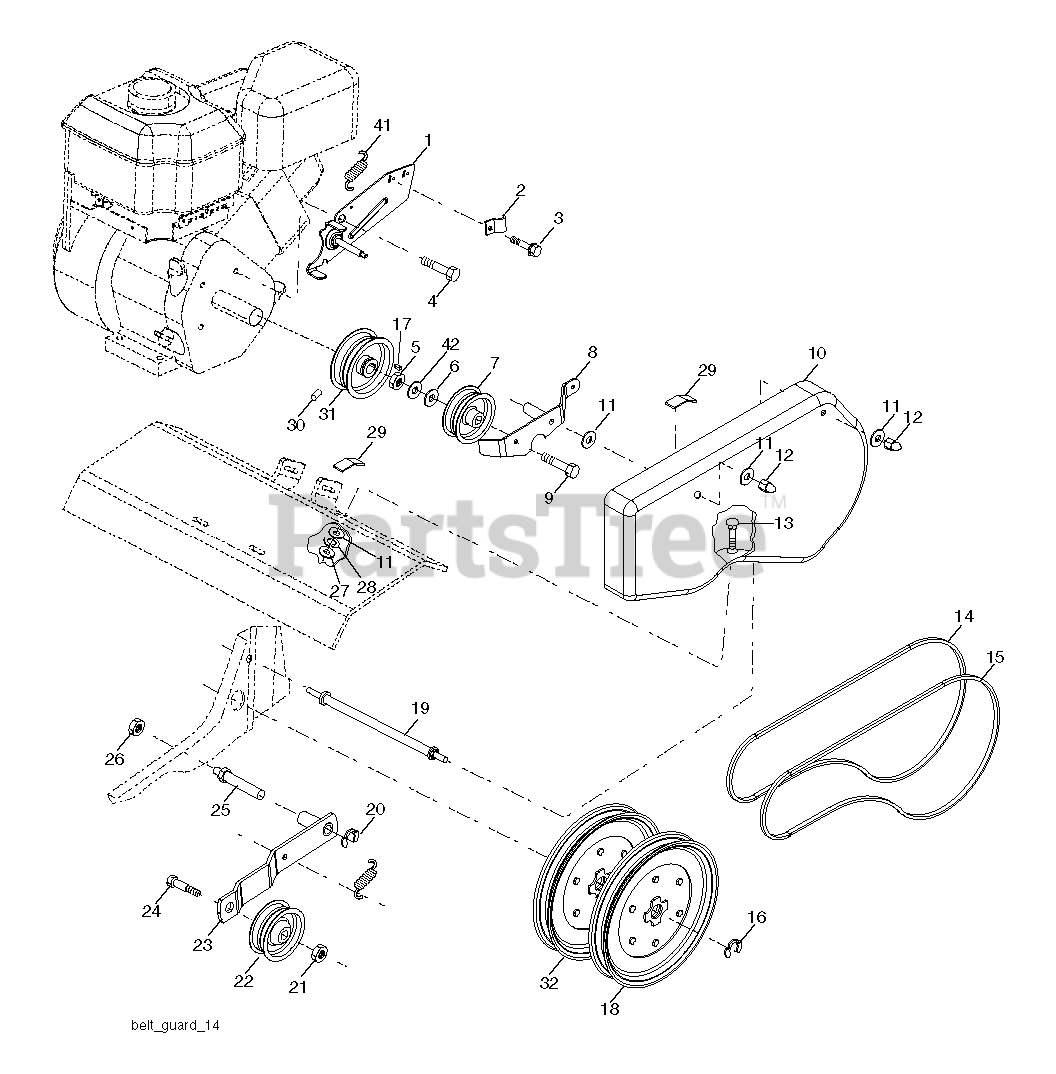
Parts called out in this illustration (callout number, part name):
1	BRACKET.ASM.GUARD.BELT.BLAC
2	CLIP.PLATED
3	TAPPING SCREW
4	Bolt, Hex Head 1/2-20 x 3/4
6	WASHER
8	ARM.ASM.REV.IDLER.TILLER.BLACK
9	CAP.SCREW.HEX.HD.3/8-16
10	GUARD.BELT.TILLER.ORANGE
12	CAP
13	BOLT
14	BELT
15	BELT.TILLER.DRIVE
16	RETAINING RING LT
17	KEY.SQ.187 X 1.125
18	SHEAVE,TRANS."D"
19	BOLT.BELT.GUARD
20	KLIP RING TI
21	NUT
22	PULLEY, IDLER
23	ARM.ASM.IDLER.
25	SHAFT.IDLER.TILLER
26	JAM NUT TI
27	NUT
28	LOCKWASHER
29	PAD IDLER TI
31	ENGINE.PULLEY.TILLER
32	SHEAVE.TRANS
41	SPRING.EXTENSION
